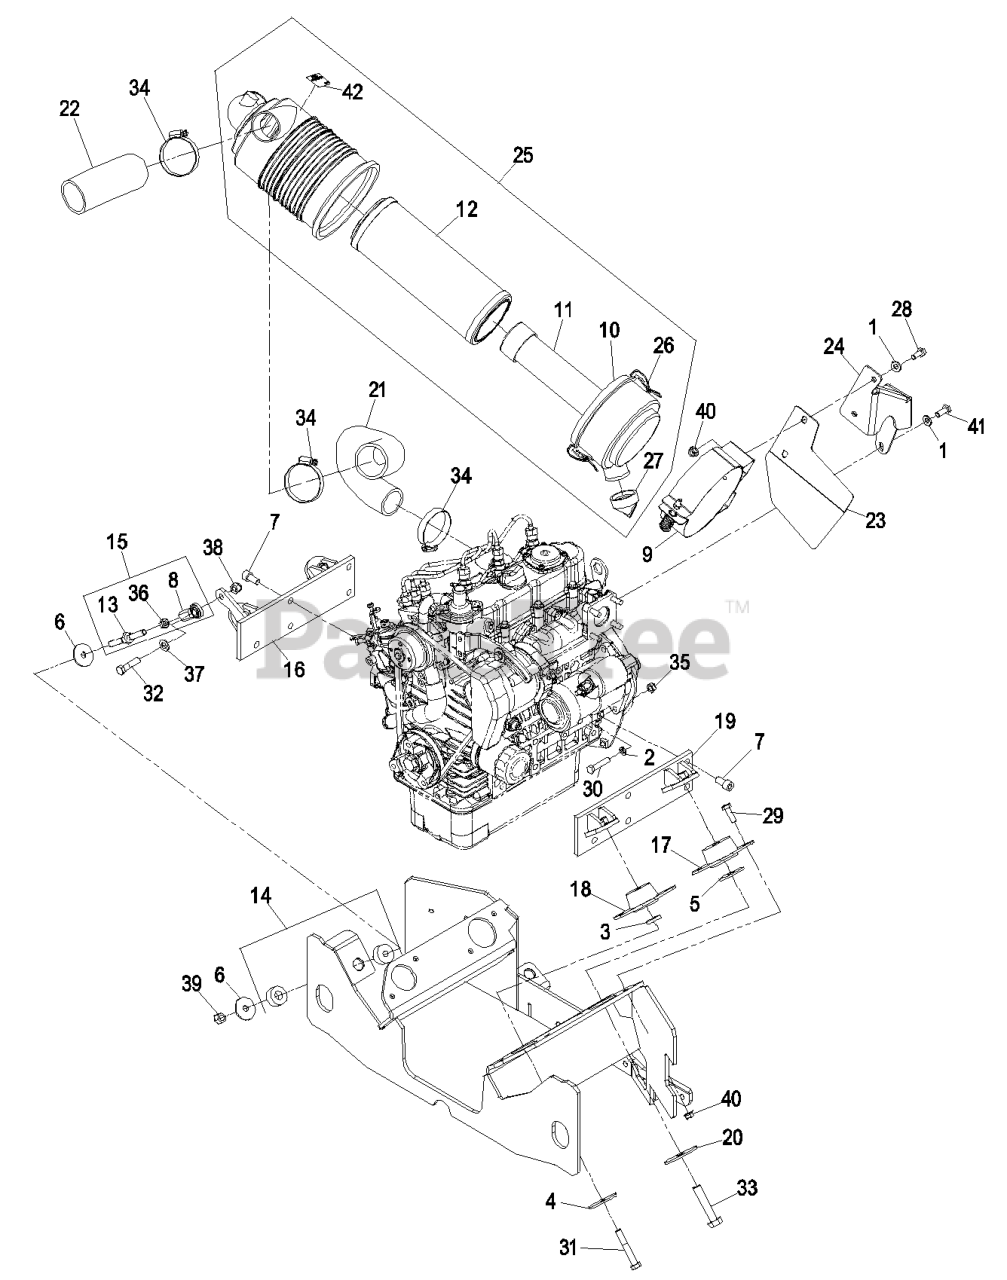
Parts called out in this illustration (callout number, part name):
1	WASHER-SPRING
2	WASHER-LOCK
4	WASHER-FLAT
5	WASHER-THRUST
7	SCREW-HSH
8	JOINT-BALL, END
9	BRACKET-FILTER, AIR
10	COVER-FILTER, AIR
11	FILTER-AIR, SAFETY
12	FILTER-AIR
13	LINK,REAR A-T AXIAL
14	ISOLATOR-LINK
15	BALL JOINT LINK ASM
16	WLD,ENG BRACKET RH SIDE
17	ISOLATOR-REAR
18	ISOLATOR-SIDE
19	WLD,ENG BRACKET LH SIDE
20	WASHER,FLAT
21	HOSE, AIRCLEANER FMZ-D
22	HOSE,AIR INTAKE
23	SHIELD,AIR CLEANER
24	WLD, BRKT AIRCLEANER FMZ-
25	ASM,AIR CLEANER W/DECALS
26	CLIP-CLEANER, AIR
27	EJECTOR, NELSON AIR CLEAN
28	SCREW-HH
29	SCREW-HH
30	SCREW-HH
31	BOLT-CARR
32	SCREW-HH
33	SCREW-HH
34	CLAMP-HOSE
35	NUT-HEX
36	NUT-HJ
37	WASHER-FLAT
38	NUT-LOCK, NI
39	NUT-LOCK
41	SCREW-HH
42	DECAL-CAUTION
